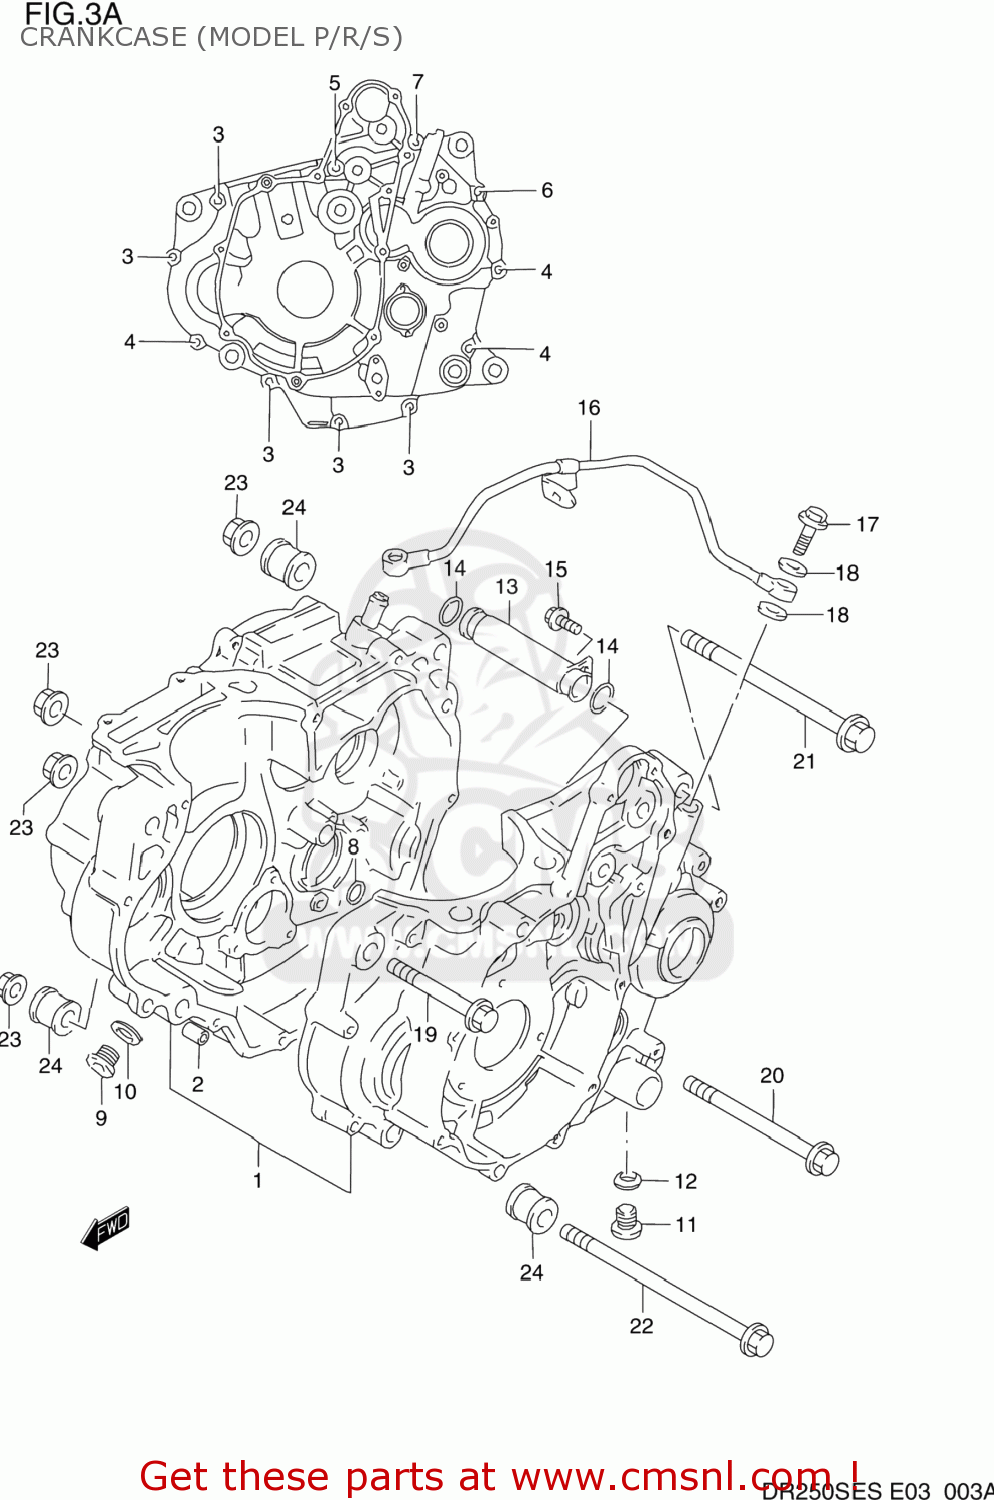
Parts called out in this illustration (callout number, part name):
1	CRANKCASE SET
2	PIN
3	BOLT
4	BOLT
5	BOLT
6	BOLT
7	BOLT
8	O-RING
9	PLUG,14X12
10	GASKET(14X19.2X2) (NAS)
11	BOLT
12	GASKET(12.1X16.2X3.7) (NAS)
13	PIPE,T/M OIL INNER
14	O RING(D:2.4,ID:15.8)
15	BOLT
16	PIPE,TRANSMISSION OIL,OUTER
17	BOLT UNION
18	GASKET 8.2X14X1 (NAS)
19	BOLT 10X85
20	BOLT(10X101.5)
21	BOLT(10X115)
22	BOLT(10X143)
23	NUT
24	SPACER,ENGINE MOUNTING
